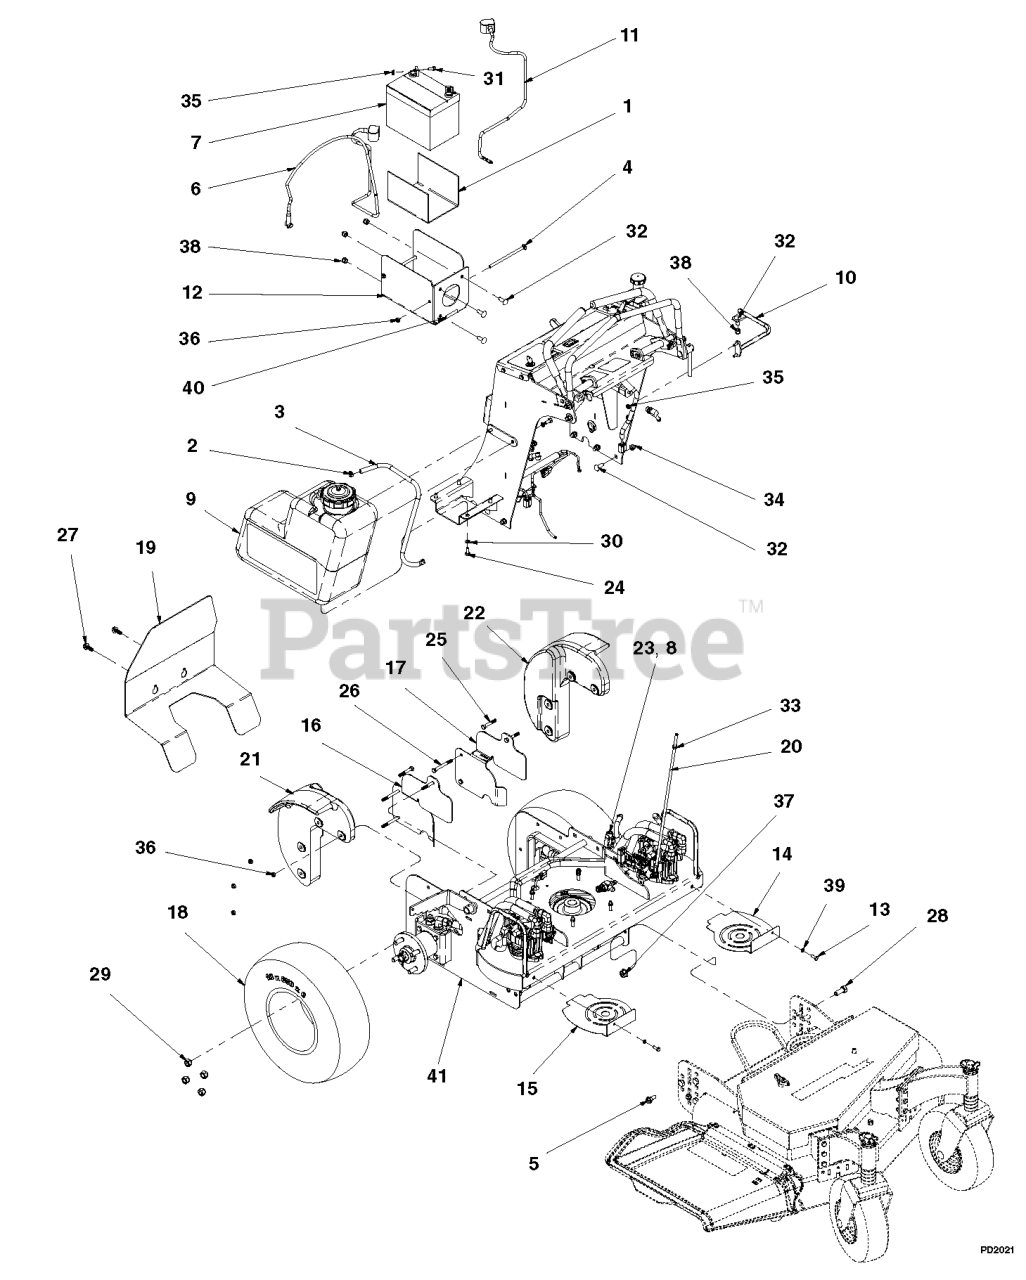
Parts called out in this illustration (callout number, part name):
1	STRIP, RUBBER
2	CLAMP, HOSE (RED) #
3	HOSE, 1/4" ID LOW PERM FUEL 50
4	BOLT, 5/16X6 LONG NK RD HD D-Z
5	BOLT, 1/2X1.06X3/8-16 SLD 5 Y
6	CABLE, BATTERY STARTER 48"
7	BATTERY, 12V-U1-CCA270MIN
8	PIN, CVS SPG 3/8" YOKE SPEC Y
9	TANK, FUEL PUPPY PAW ASSEMBLY
10	WLDT, RESERVOIR GUARD
11	CABLE, BATTERY - 25" GROUND
12	CONSLE BTRY BRKT W/DCAL GDN 34
13	BOLT, 1/4-20X.750 HEX 5 Y
14	SHIELD, LH PUMP BLACK
15	SHIELD, RH PUMP (BLACK)
16	SHIELD, RH MOTOR W/DECAL
17	SHIELD, LH MOTOR W/DECAL
18	ASSY, TIRE/WHL 18-6.50-8
19	SHIELD, ENGINE W/DECALS GDANE
20	ROD, CONTROL 5/16-24 X 22.75 Y
21	RH CAST WEIGHT MACHINED
22	LH CAST WEIGHT MACHINED
23	YOKE, 3/8-24 RH ADJUSTABLE
24	BOLT, 5/16-18X.750 HEX 5 Y
25	BOLT, 5/16-18X2.00 HEX 5 Y
26	BOLT, 5/16-18X3.00 HEX 5 Y
27	BOLT, 3/8-16X1.00 FGH 8 Y
28	BOLT, 1/2-13X1.25 HEX 5 Y
29	NUT, 1/2-20 LUG C
30	WASHER, .313 MED SPRG LOCK Y
31	BOLT, 1/4-20X.625 WSH Y
32	BOLT, 3/8-16X1.00 CRG 5 SN Y
33	NUT, 5/16-24 STD HEX GR5 Y
34	LOCKNUT, 3/8-16 WHIZ Y
35	LOCKNUT, 1/4-20 WHIZ Y
36	LOCKNUT, 5/16-18 NYLOC Y
37	LOCKNUT, 1/2-13 WHIZ GR5 Y
38	LOCKNUT, 3/8-16 NYLOC Y
39	WASHER, .250 MED SPRG LOCK Y
40	TRIM, RUBBER EDGE 2"
41	Power Unit 19 Narrow
